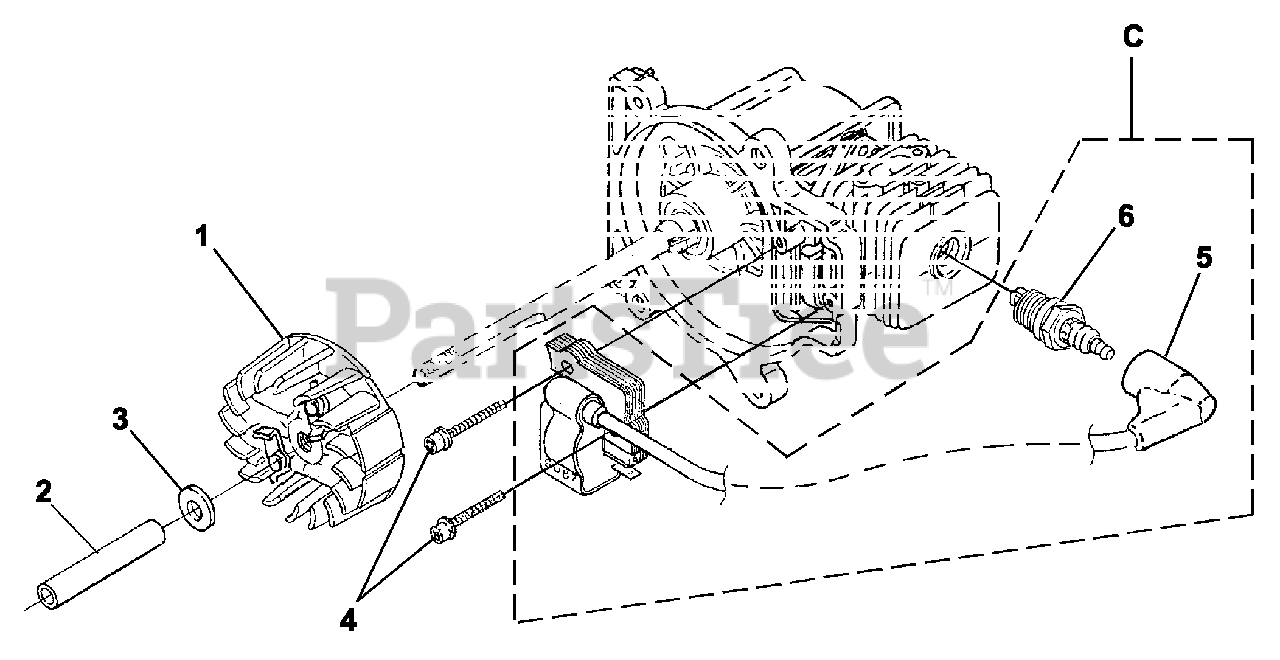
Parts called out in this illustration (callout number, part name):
1	Rotor & Starter Pawls
2	Spacer
3	Washer, Flat
4	Screw-Thread Forming (8-32 X 1)
5	Terminal & Cover
6	Resistor Spark Plug (RDJ-7Y)
C	Ignition Kit
